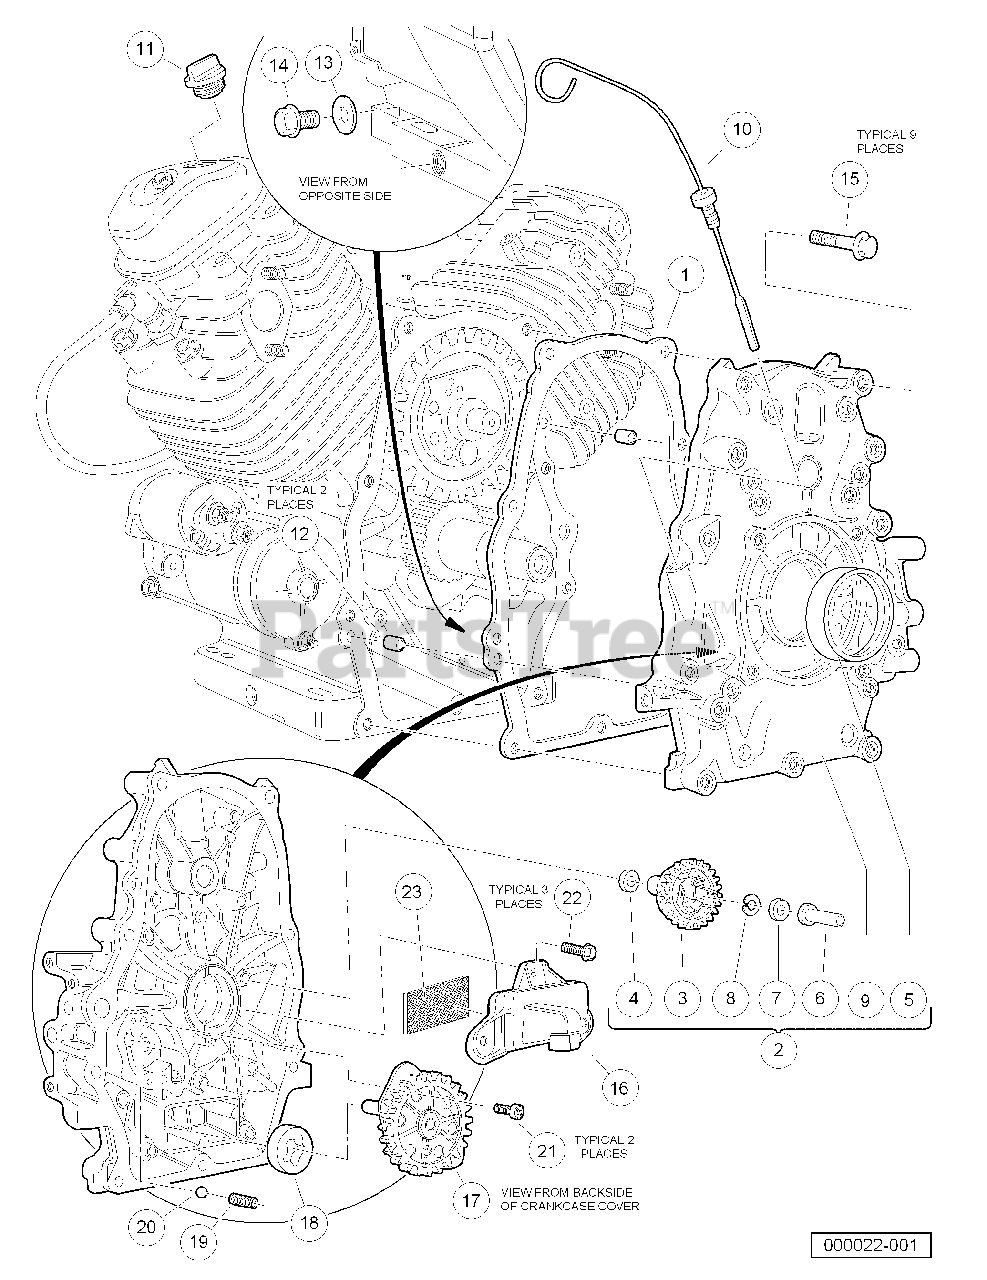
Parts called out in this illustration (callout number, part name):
1	Gasket, Case Cover
2	Cover Assembly, Crankcase
3	Governor Assembly
4	Washer, Plain, M6
5	Seal, Oil, 38 X 58 X 9
6	Slider, Governor
7	Washer, 6 X 16
8	Clip, Governor
9	Cover, Crankcase
10	Dipstick, Oil
11	Cap, Oil Filler
12	Pin A, Dowel, 8 X 14
13	Washer, Drain Plug, M14
14	Bolt, Drain Plug , M14
15	Bolt, Flange Head, M8 X 1.25 X 50
16	Cover, Oil Filter
17	Cover Assembly, Oil Pump
18	Rotor, Oil Pump, Outer
19	Spring, Relief Valve
20	Ball, Steel , 3/8, #12
21	Bolt, Socket
22	Bolt, Flange Head, M6 X 1 X 20
23	Screen, Oil Filter
